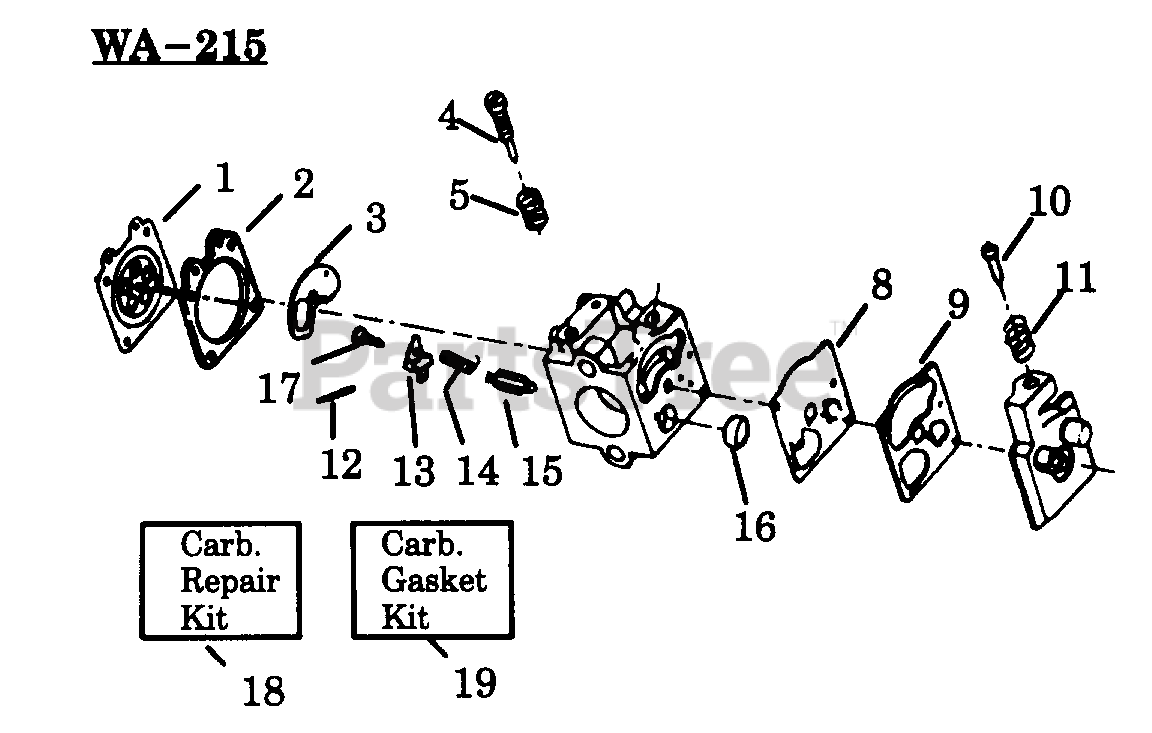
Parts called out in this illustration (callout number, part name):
1	Metering Diaphram
2	Metering Diaphragm Gasket
3	Circuit Plate Gasket
4	Mixture Needle
5	Mixture Needle Spring
8	Fuel Pump Diaphragm
9	Fuel Pump Gasket
10	Idle Speed Screw
11	Idle Speed Spring
12	Metering Lever Pin
13	Metering Lever
14	Metering Lever Spring
15	Inlet Needle Valve
16	Fuel Inlet Screen
17	Metering Lever Pin Screw
18	Carb. Kwik Repair Kit (Inc. 1,2,3,8,9,12, 13,14,15,16,17)
19	Carb. Gasket/Diaphragm Kit (Inc. 1,2,3,8,9)
